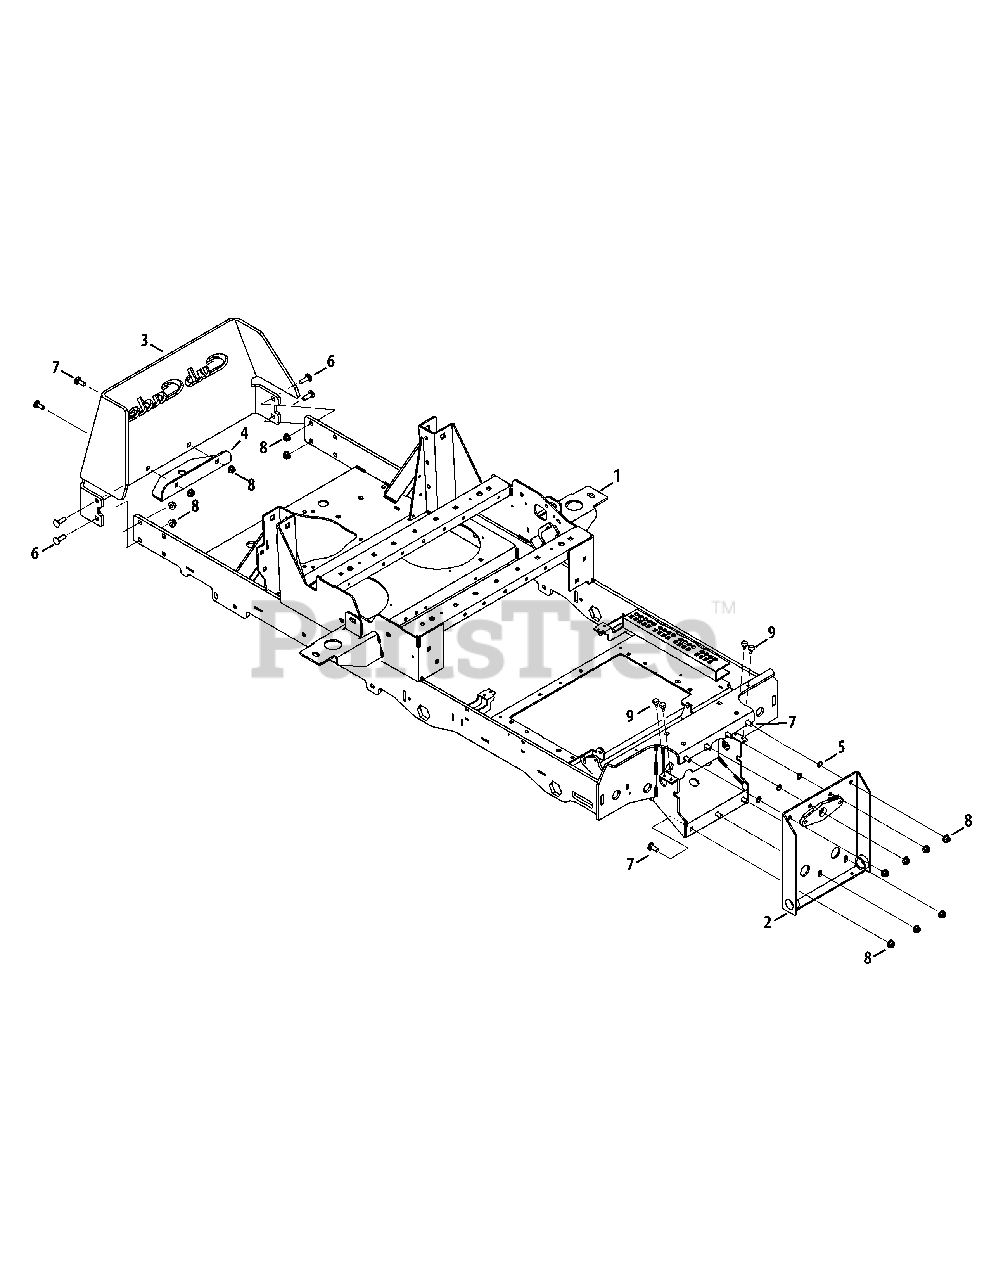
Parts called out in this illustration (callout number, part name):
1	Frame Assembly
2	Front Axle Bracket Assembly
5	Push Nut, 3/8
6	Carriage Bolt, 3/8-16 x 1.25
7	Carriage Bolt, 3/8-16 x 1.00
8	Nylock Nut, 3/8-16
9	Bumper, .62 Dia. x .3
